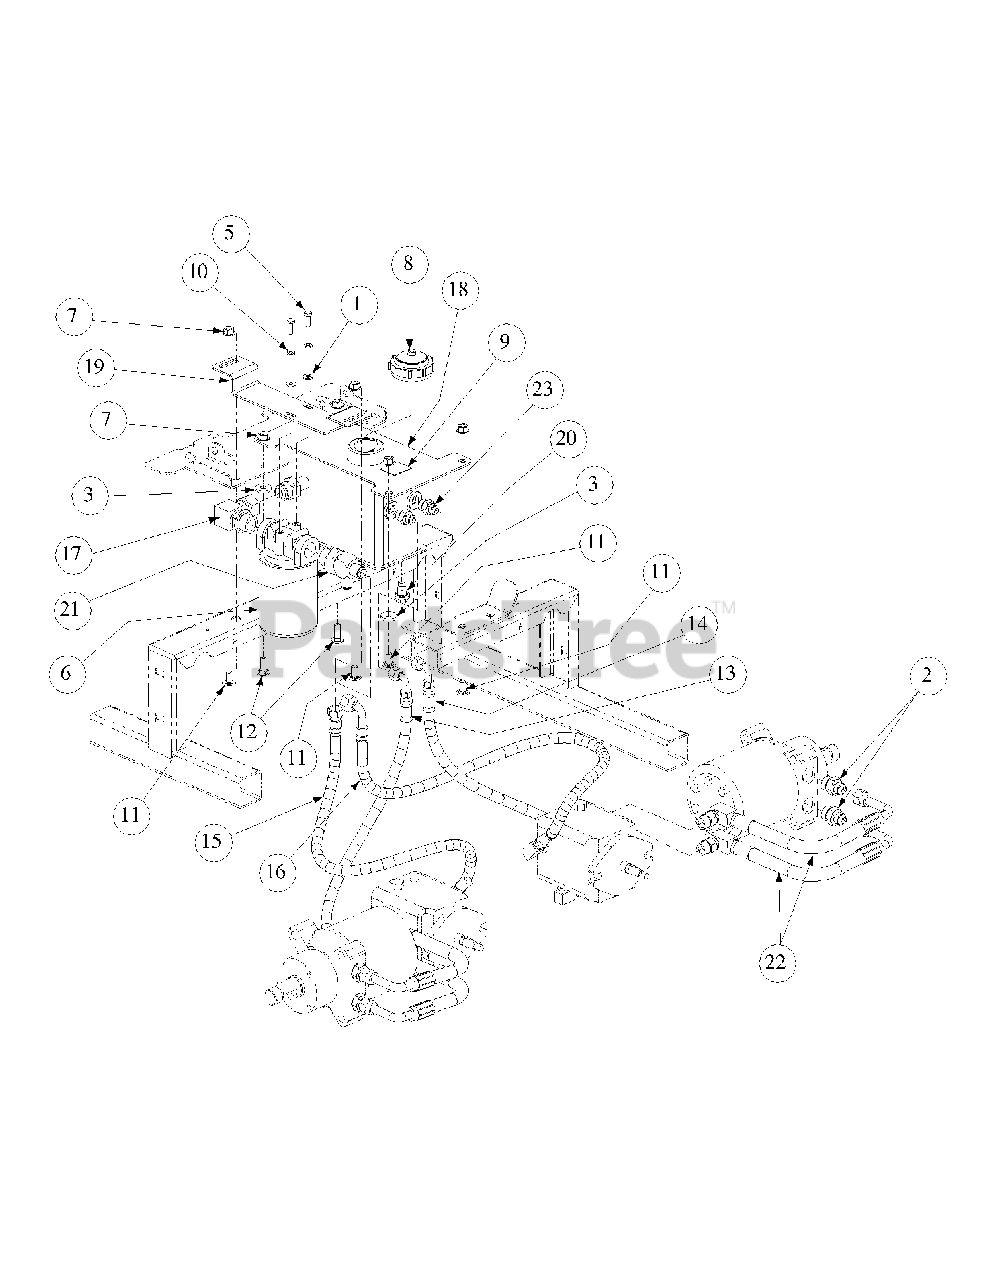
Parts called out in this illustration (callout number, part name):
1	Washer, 1/4
2	Fitting 1/2 x 3/4 - O Ring
3	Washer, .406 x 1.0 OD x .105
4	Cable Tie, 3/16 x .05 x 7.4
5	Hex Cap Screw, 1/4-20, .75
6	Filter Head 3/4
7	Hex Nut Flange Lock, 3/8-16
8	Cap, Hydro Oil Tank
9	Decal Oil Only 5W40
10	Lock Washer, 1/4
11	Carriage Bolt, 3/8-16 x .75 LG.
12	Carriage Bolt, 3/8-16 x 1.00
13	28.87" Return Hose Assembly
14	31.88" Return Hose Assembly
15	29.25" Supply Hose Assembly
16	40.31 Supply Hose Assembly
17	Fitting Elbow, 90
18	Hydraulic Tank Assembly
19	Filter Mounting Bracket
20	Oil Pan Drain w/ Seal and Plug
21	Tee Fitting, 3/4 x 1/2 x 1/2
22	Hydraulic Hose
23	Fitting 1/2 x 3/8
